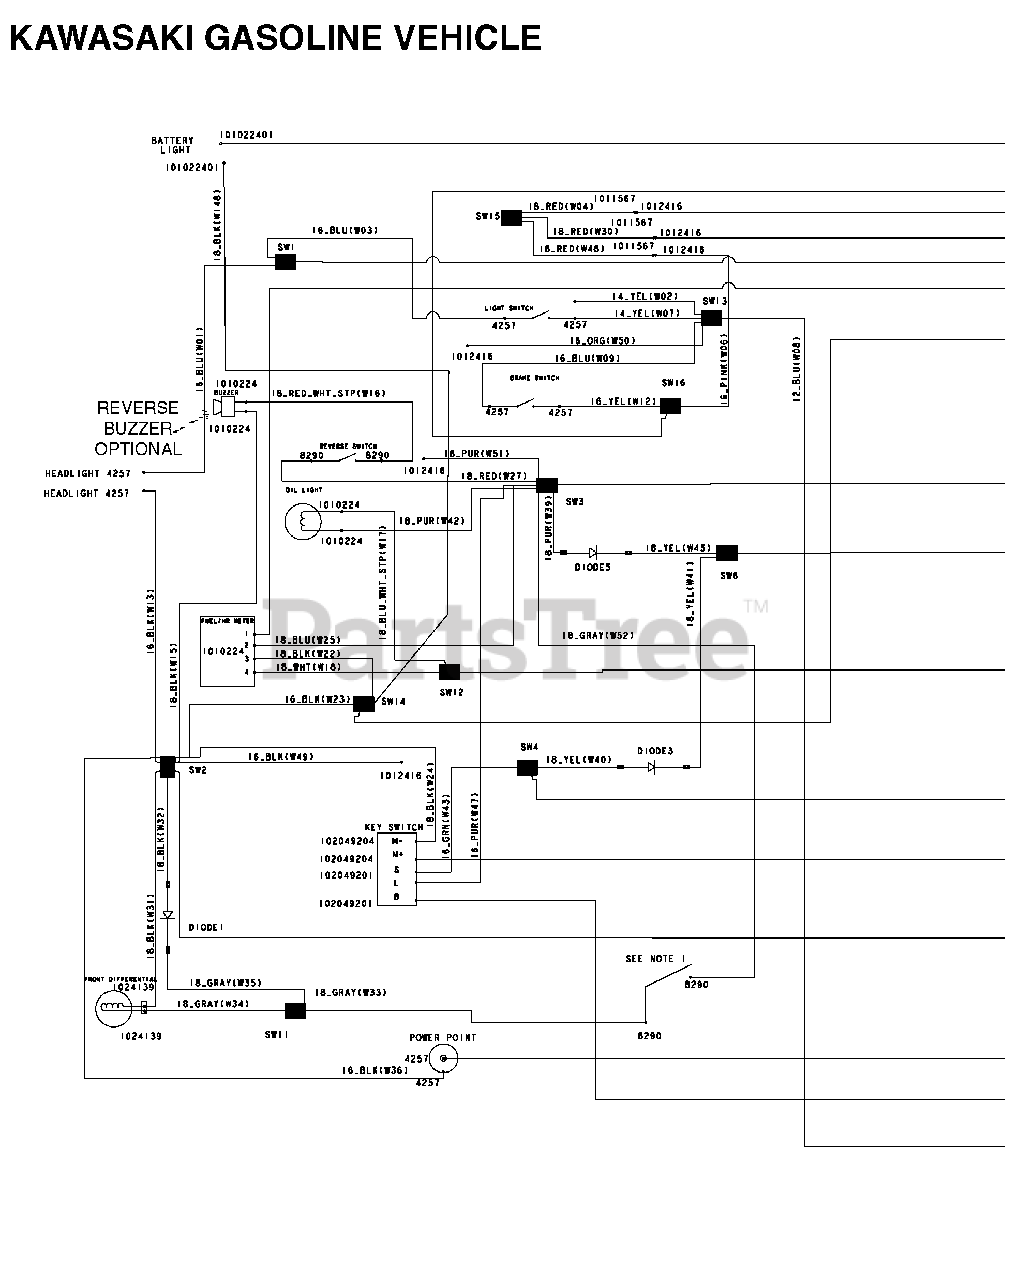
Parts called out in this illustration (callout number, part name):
1	Diode, General Purpose, 6.0a
2	Harness, AWD, Kawasaki, Stretch
3	Asm, Switch, Limit, Awd
